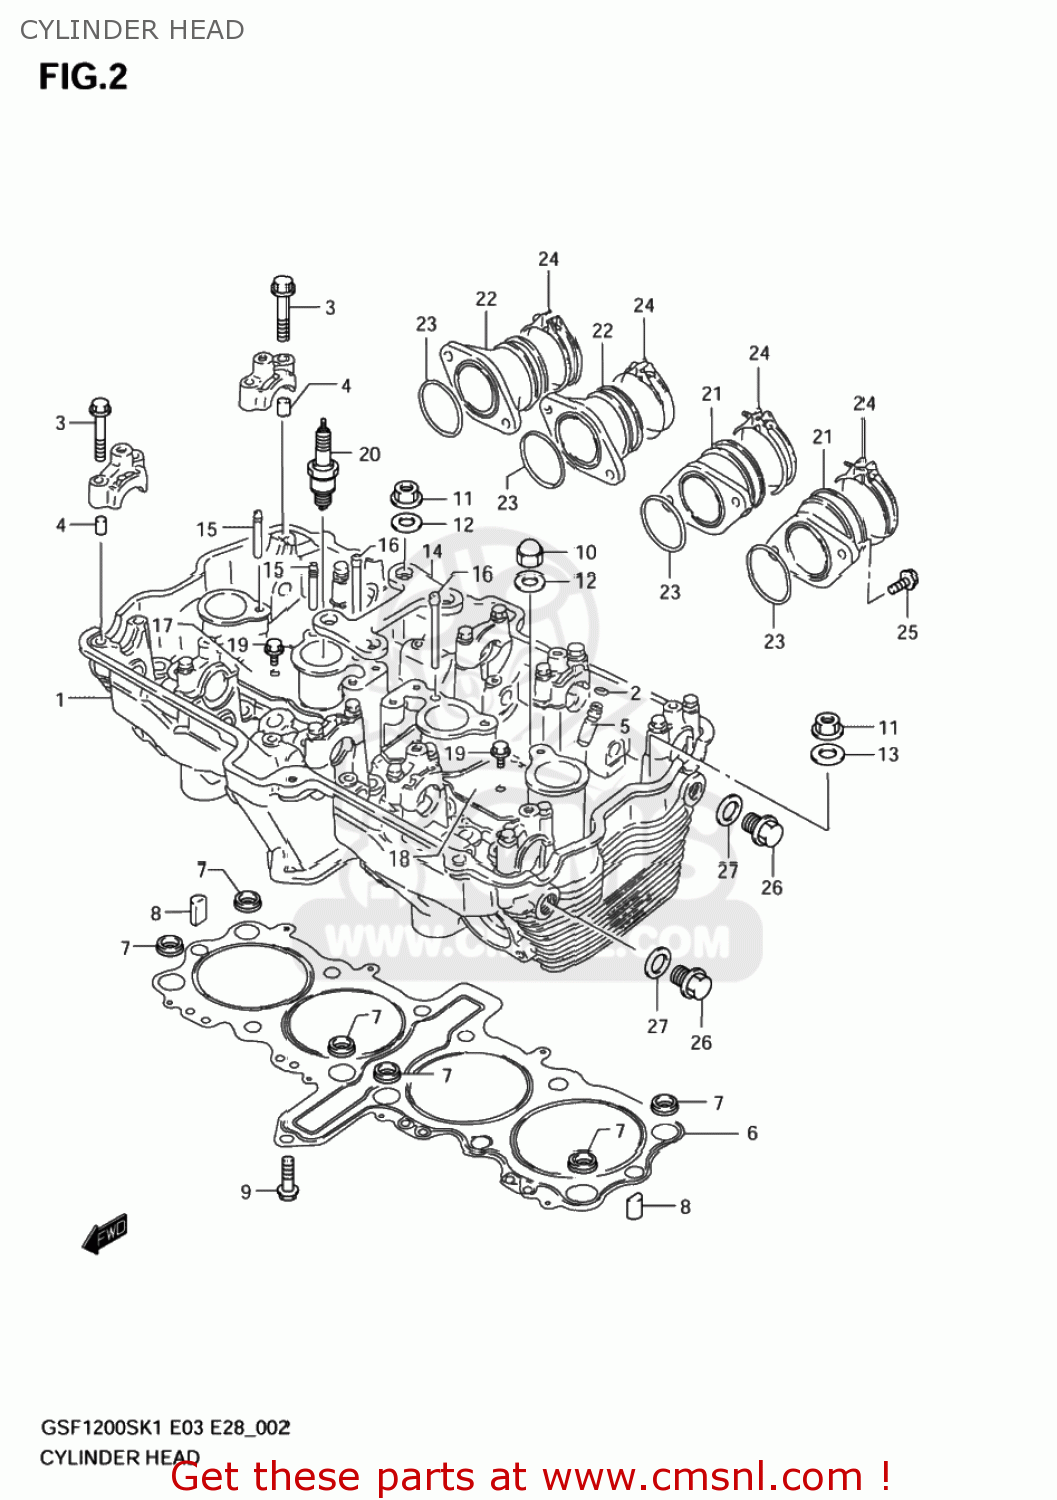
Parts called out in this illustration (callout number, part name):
1	HEAD ASSY,CYLINDER
2	RING,SNAP
3	BOLT(6X39)
4	PIN(6.2X8X11)
5	GUIDE,VALVE
6	GASKET,CYLINDER HEAD (NAS)
7	O RING,HEAD GASKET
8	PIN
9	BOLT
10	NUT
11	NUT
12	GASKET(10.2X20X2).3 (NAS)
13	WASHER (10.5X22X2.3)
14	PLATE,HEAD REINFORCEMENT
15	PIPE,OIL NO.1
16	PIPE,OIL NO.3
17	PLATE,OIL PIPE,R
18	PLATE,OIL PIPE,L
19	BOLT
20	PLUG,SPARK(JR9B)
21	PIPE ASSY,INTAKE,L
22	PIPE ASSY,INTAKE,R
23	O RING(D:2.4,ID:41.7)
24	CLAMP
25	BOLT MAGNETO S
26	PLUG
27	GASKET(13.8X18.8X4.8) (NAS)
